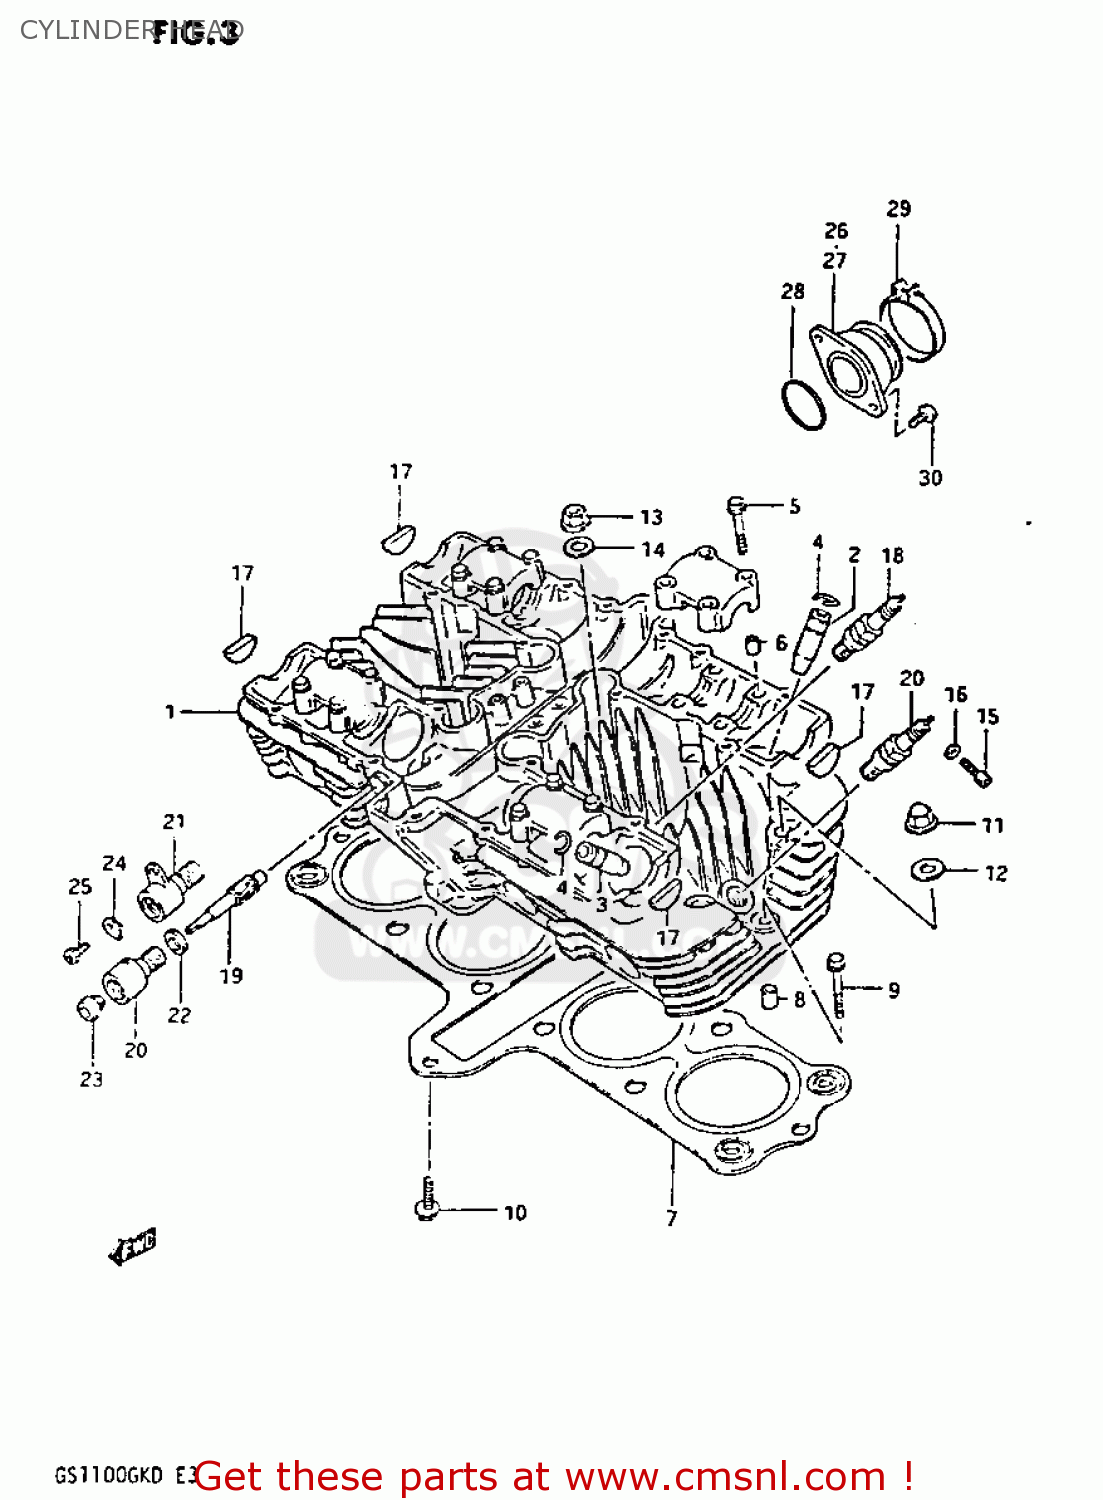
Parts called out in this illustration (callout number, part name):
1	HEAD ASSEMBLY,CYLINDER
2	GUIDE,INTAKE VALVE
3	GUIDE,EXHAUST VALVE
4	RING,SNAP
5	BOLT(6X39)
6	PIN(6.2X8X11)
7	GASKET,CYLINDER HEAD (NAS)
8	PIN
9	BOLT,UNDER
10	BOLT
11	NUT
12	GASKET(10.5X22X2) (NAS)
13	NUT
14	WASHER(10.5X22X2.3)
15	SCREW (5X10)
16	GASKET(5.3X9.3X1.2) (NAS)
17	PLUG
18	PLUG,SPARK
19	GEAR,TACHOMETER DRIVEN
20	SLEEVE,TACHOMETER DRIVE GEAR
21	SLEEVE,TACHOMETER DRIVE GEAR
22	SEAL,TACHOMETER DRIVEN
23	SEAL,OIL(5X12X8)
24	PLATE,TACH DRIVE GEAR SLEEVE
25	SCREW(5X12)
26	PIPE,INTAKE,R
27	PIPE,INTAKE,L
28	O-RING (D:2.4 ID:39.7)
29	CLAMP
30	SCREW
